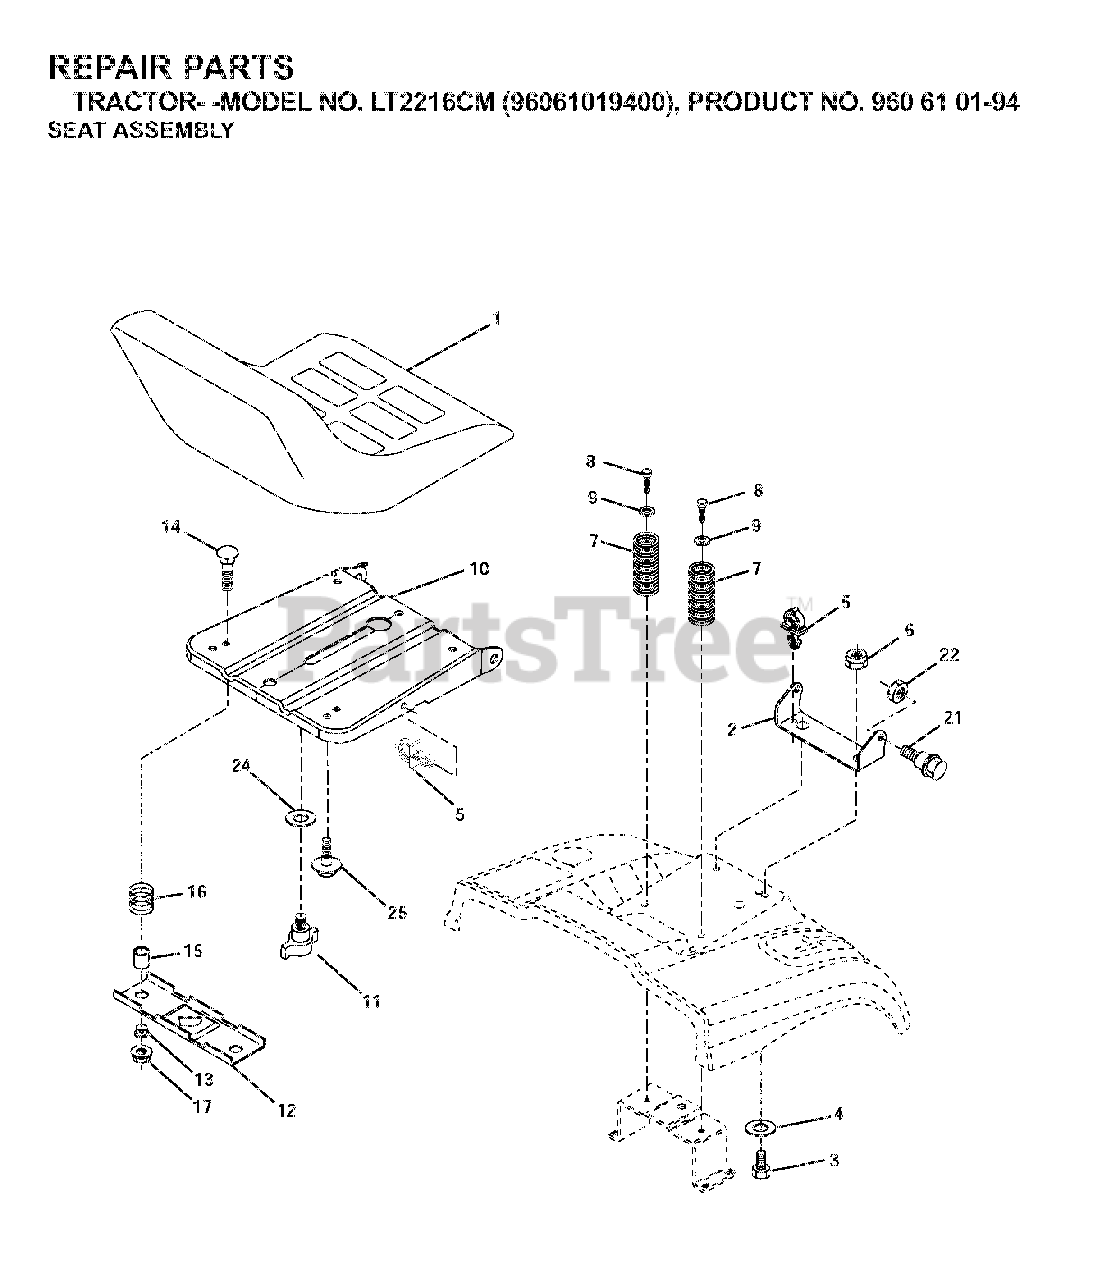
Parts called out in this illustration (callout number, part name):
2	SEAT PIVOT BRKT
4	WASHER PM
5	PUSH CLIP
6	NUT
7	SPRING COMPRESSION
8	SCREW 3/8-16X1
9	WASHER
10	PAN.ASM.SEAT.1SLOT
11	KNOB.SEAT.ADJ.WINGNUT
12	BRKT.MNTNG.SWITCH.SEAT
14	BOLT.ROUND.HEAD.SQUARE.NECK
15	SPACER SPLIT 28X.96
17	NUT T
21	BOLT.SHOULDER.5/16-18
22	NUT.71038.31-18.HEX.NYLOCK
25	BOLT,SHOULD
